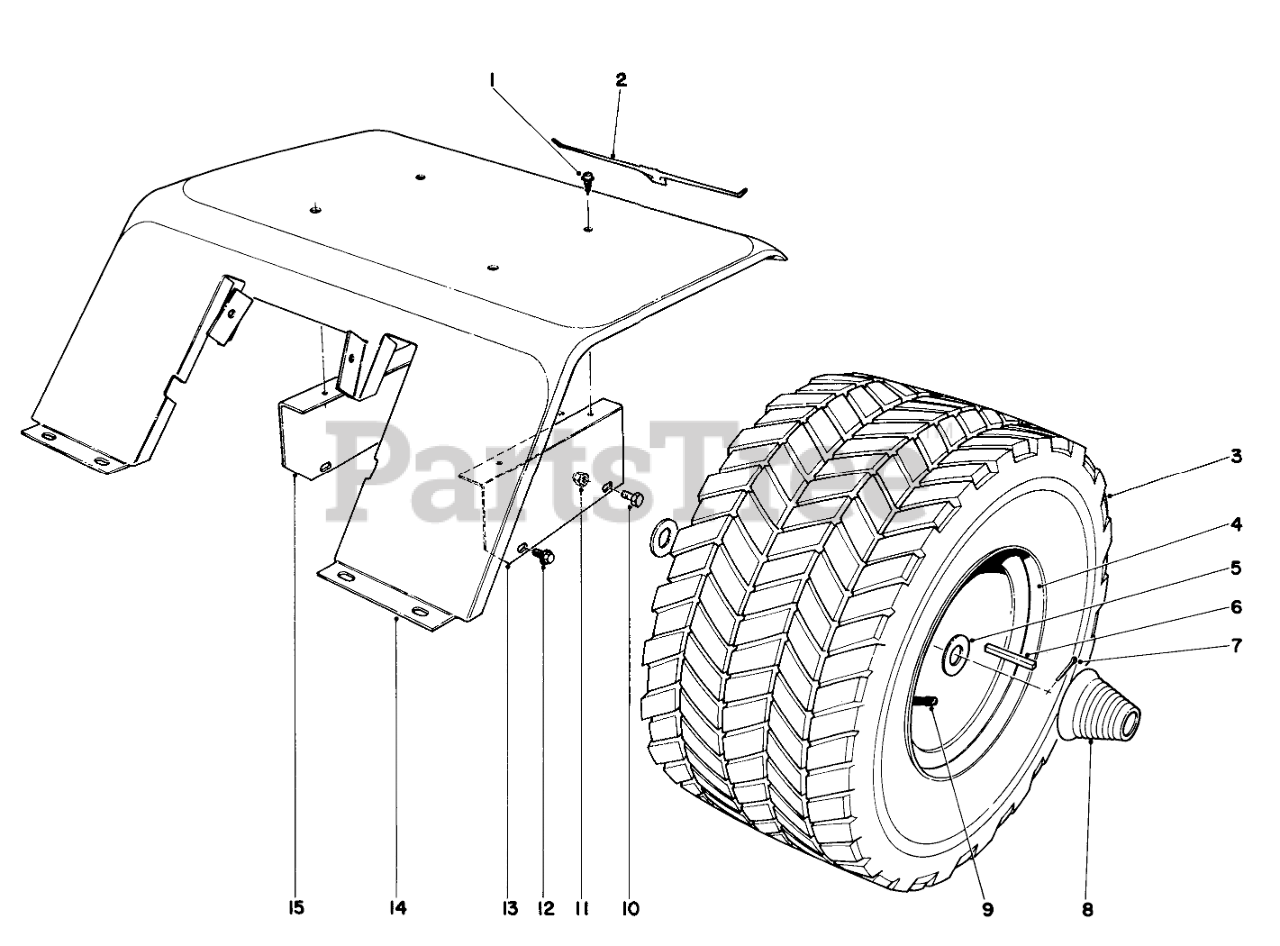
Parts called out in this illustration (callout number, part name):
1	10-16 X 3/8 THDG SCREW
2	Decal
5	Waxer
7	PIN-COTTER
8	Hub Cap
9	VALVE -STEM
10	SCREW-HH
11	Nut
13	Fender Support L.H.
14	Fender
15	Fender Support R.H.
